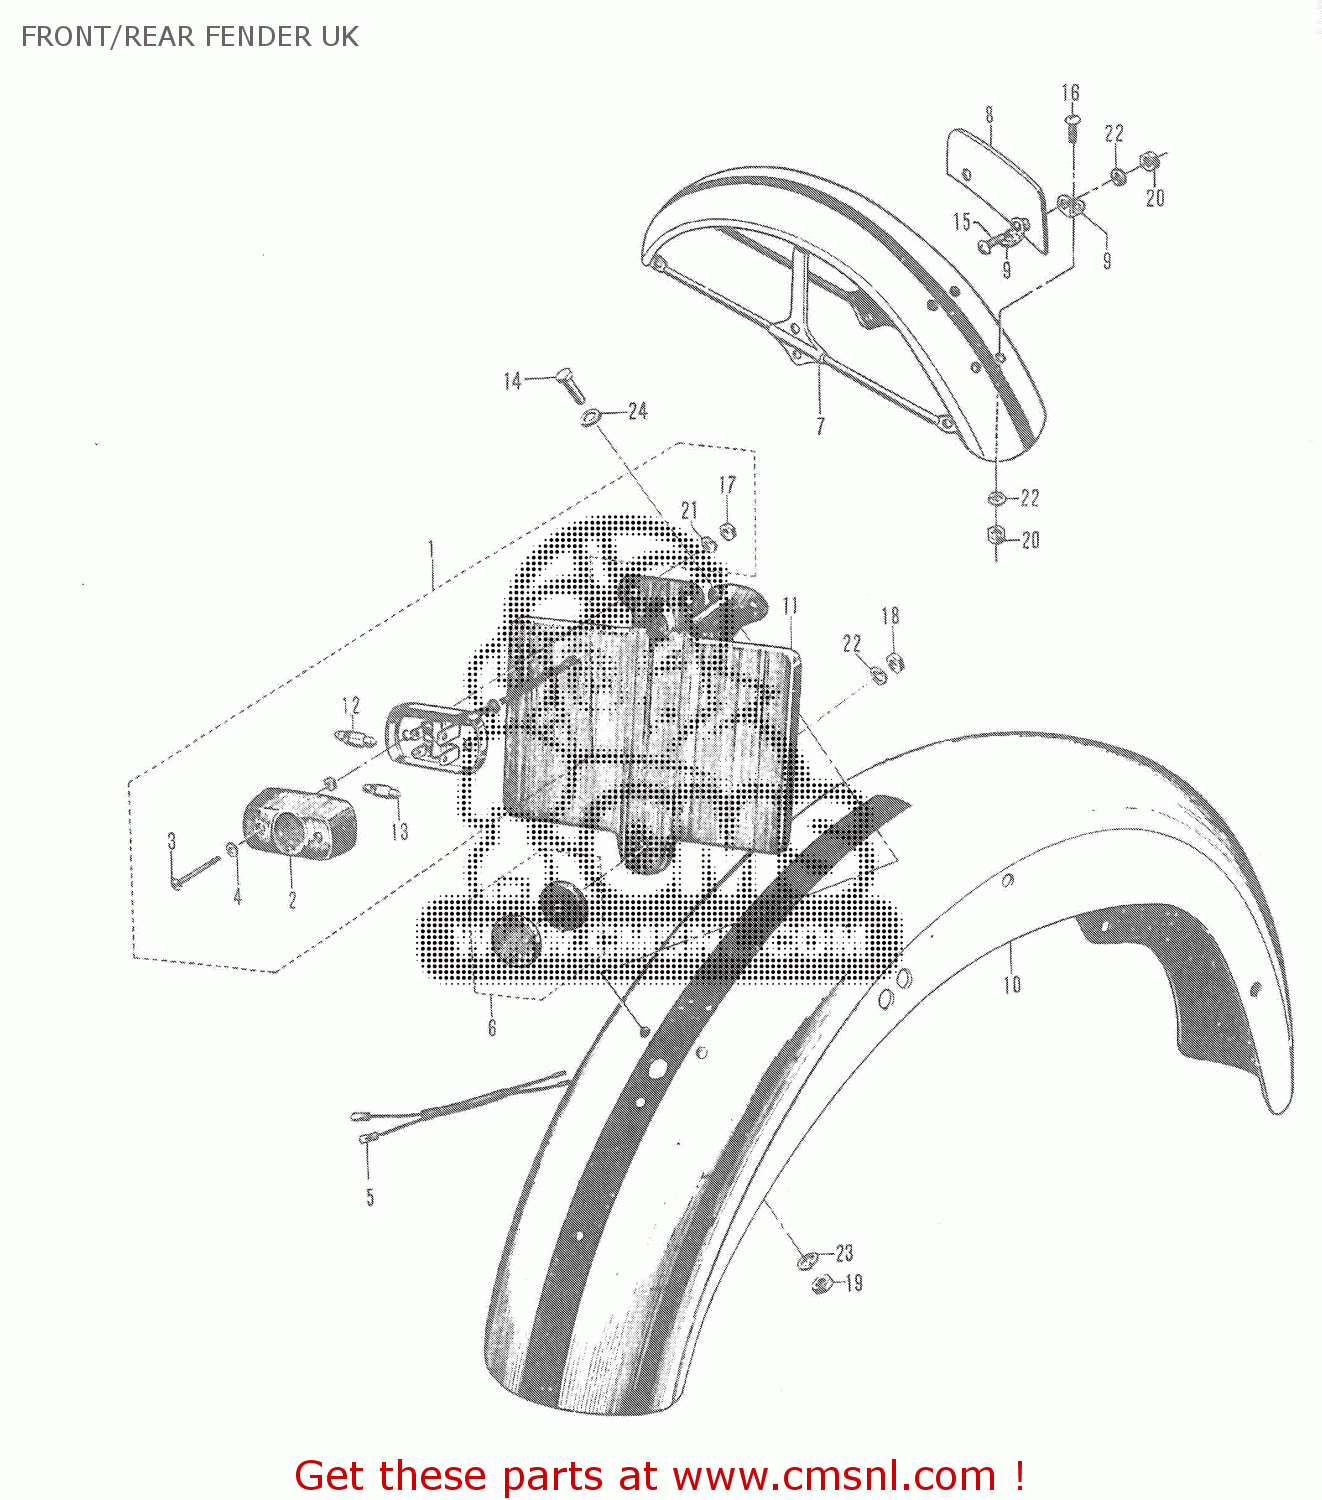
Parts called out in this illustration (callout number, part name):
1	TAIL/BRAKE LAMP ASS'Y
2	TAIL/BRAKE LAMP LENS
3	TAIL/BRAKE LAMP LENS SCREW
4	WASHER,REAR COMBINATION LAMP
5	TAIL/BRAKE LAMP WIRING HARNESS
6	REFLECTOR
7	FRONT FENDER
8	PLATE, FRONT LICENCE
9	PLATE, LICENCE FITTING
10	REAR FENDER
11	REAR LICENCE NUMBER PLATE
12	BRAKE LAMP BULB
13	TAIL LAMP BULB
14	HEXAGON BOLT
15	CROSS HEAD SCREW
16	CROSS HEAD SCREW
17	HEXAGON NUT
18	HEXAGON NUT
19	HEXAGON NUT
20	HEXAGON NUT
21	LOCK WASHER
22	LOCK WASHER
23	LOCK WASHER
24	FLAT WASHER
